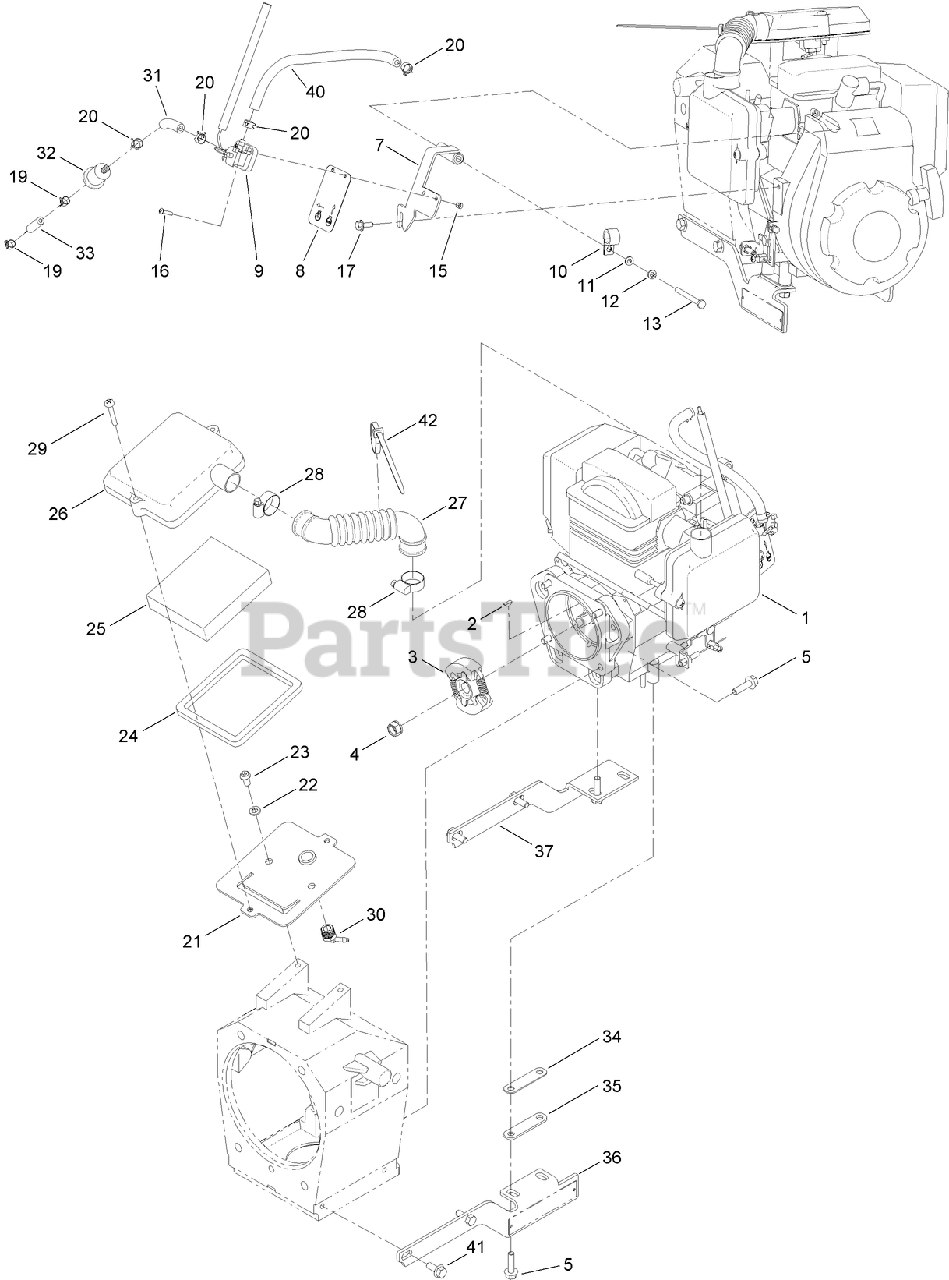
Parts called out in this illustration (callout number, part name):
1	ENGINE-HONDA, GX100
2	KEY-WOODRUFF
3	CLUTCH-FRICTION
4	NUT-HEX FLANGE
5	SCREW-HHF
7	BRACKET-FUEL VALVE
8	HANG TAG-RUN, STOP
9	FUEL SHUT OFF VALVE ASM
10	CLAMP-CABLE
11	WASHER-FLAT
12	WASHER-LOCK, SPRING
13	SCREW-HH
15	NUT-LOCK
16	SCREW-HSBH
17	SCREW-HH
19	CLAMP-HOSE
20	CLAMP-HOSE
21	BASE-PREFILTER
22	WASHER-LOCK
23	SCREW-HSBH
24	GASKET-PREFILTER
25	FILTER-AIR, PREFILTER
26	COVER-AIR FILTER
27	TUBE-AIR
28	CLAMP-WORM
29	SCREW-PPH
30	FITTING-90 DEG
31	HOSE-FUEL
32	FILTER-FUEL
33	HOSE-FUEL
34	SHIM-ENGINE (16GA)
35	SHIM-ENGINE (11GA)
36	BRACKET-SUPPORT, LH
37	BRACKET-SUPPORT, RH
40	HOSE-FUEL
41	SCREW-HHF
42	TIE-PLASTIC
